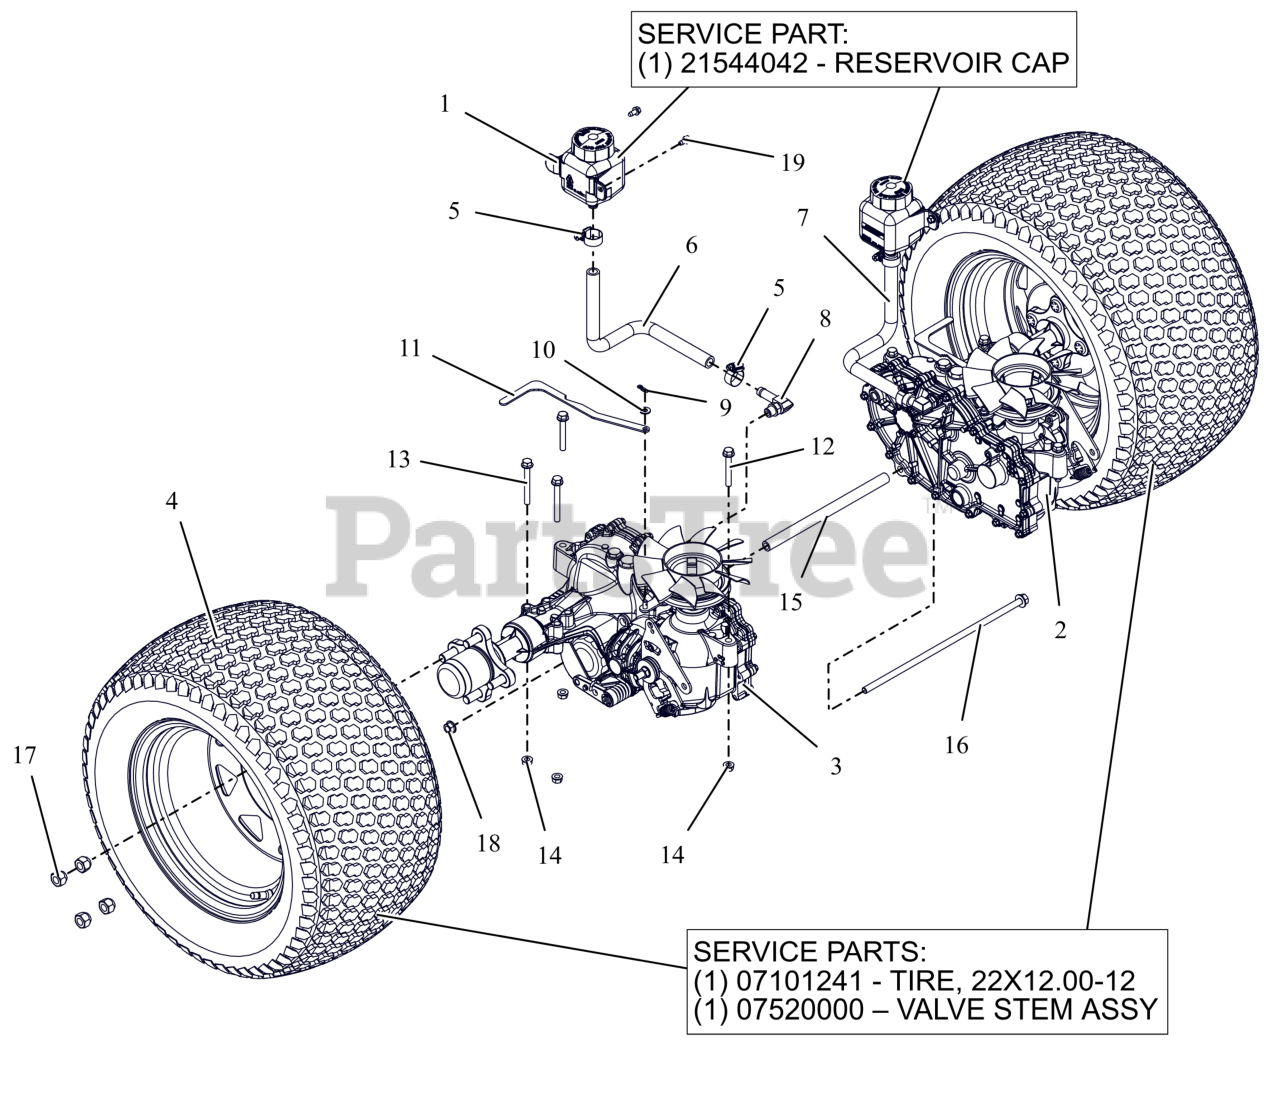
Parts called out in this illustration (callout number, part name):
1	TANK, EXPANSION
1	CAP, HYDRO RESERVOIR REPLAC.
2	TRANSAXLE, ZT3100 - LH
3	TRANSAXLE, ZT3100 - RH
4	ASM, WHL/TIRE 22X12-12 LG BLK
4	TIRE, 22X12.00-12
4	VALVE STEM ASS'Y
4	TUBE 22,23&24X8.50/9.50/10.00/10.50/12.00-12
5	CLAMP,.88 DIA. HOSE
6	HOSE, FORMED EXPANSION -HD RH
7	HOSE, FORMED EXPANSION -HD LH
8	FITTING, HYD (90 DEG)
9	PIN, HAIR #225 .072X1.09
10	WSHR,FLT .281X.625X.065 ZCC
11	BRKT, VALVE DUM
12	BLT,HEX-FLG .31-18X2.25 G5 ZCC
13	BLT,HEX-FLG .31-18X2.75 G5 ZCC
14	NUT,LK-CTR-FLG .31-18 GF ZCC
15	SPCR, TRANSAXLE .406 ID X .630 OD X 9.95LG (BLACK)
16	BLT, HEX-FLG 0.375-16X13 GR5 ZC120
17	NUT, WHEEL .50-20 ZCC
18	NUT-LK-TOP-FLG .38-16 ZC120
19	SCR-TAP .25-20X.50 HWH ZCC
